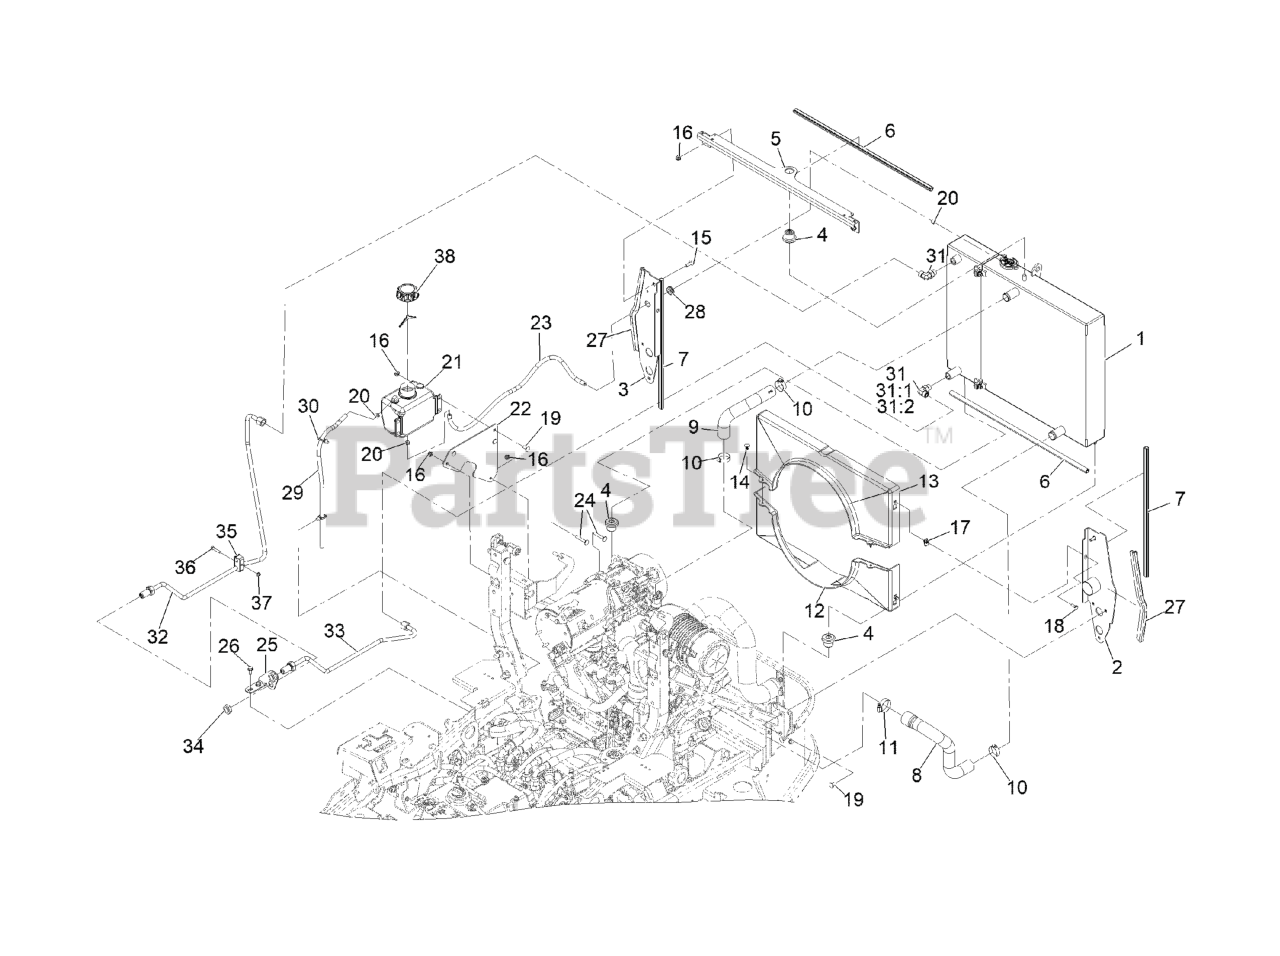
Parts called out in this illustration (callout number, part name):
1	COOLING ASM
2	SUPPORT-RADIATOR, LH
3	SUPPORT-RADIATOR, RH
4	MOUNT-ISOLATOR
5	BRACKET-COOLING, TOP
6	SEAL-BULB
7	SEAL-BULB
8	HOSE-RADIATOR, LOWER
9	HOSE-RADIATOR, UPPER
10	CLAMP-HOSE
11	CLAMP-HOSE
12	SHROUD-BOTTOM
13	SHROUD-TOP
14	PLUG-PLASTIC
15	SCREW-HHF
16	NUT-HF, NI
18	SCREW-HWH
19	SCREW-CARR
20	CLAMP-HOSE
21	TANK-OVERFLOW, W/CAP
22	BRACKET-BOTTLE
23	HOSE-FUEL
24	BOLT-CARR
25	BRACKET-BULKHEAD
26	Screw-HWH 5/16-18 X 3/4 Tf
27	SEAL-BULB
28	GROMMET
29	HOSE-FUEL
30	CLIP-TIE
31	FITTING-ELBOW, 90 DEG
31:1	O-RING
31:2	O-RING
32	HYDRAULIC TUBE ASM
33	HYDRAULIC TUBE ASM
34	NUT-BULKHEAD
35	CLAMP-TWIN
36	SCREW-HH
38	CAP-W/TETHER
